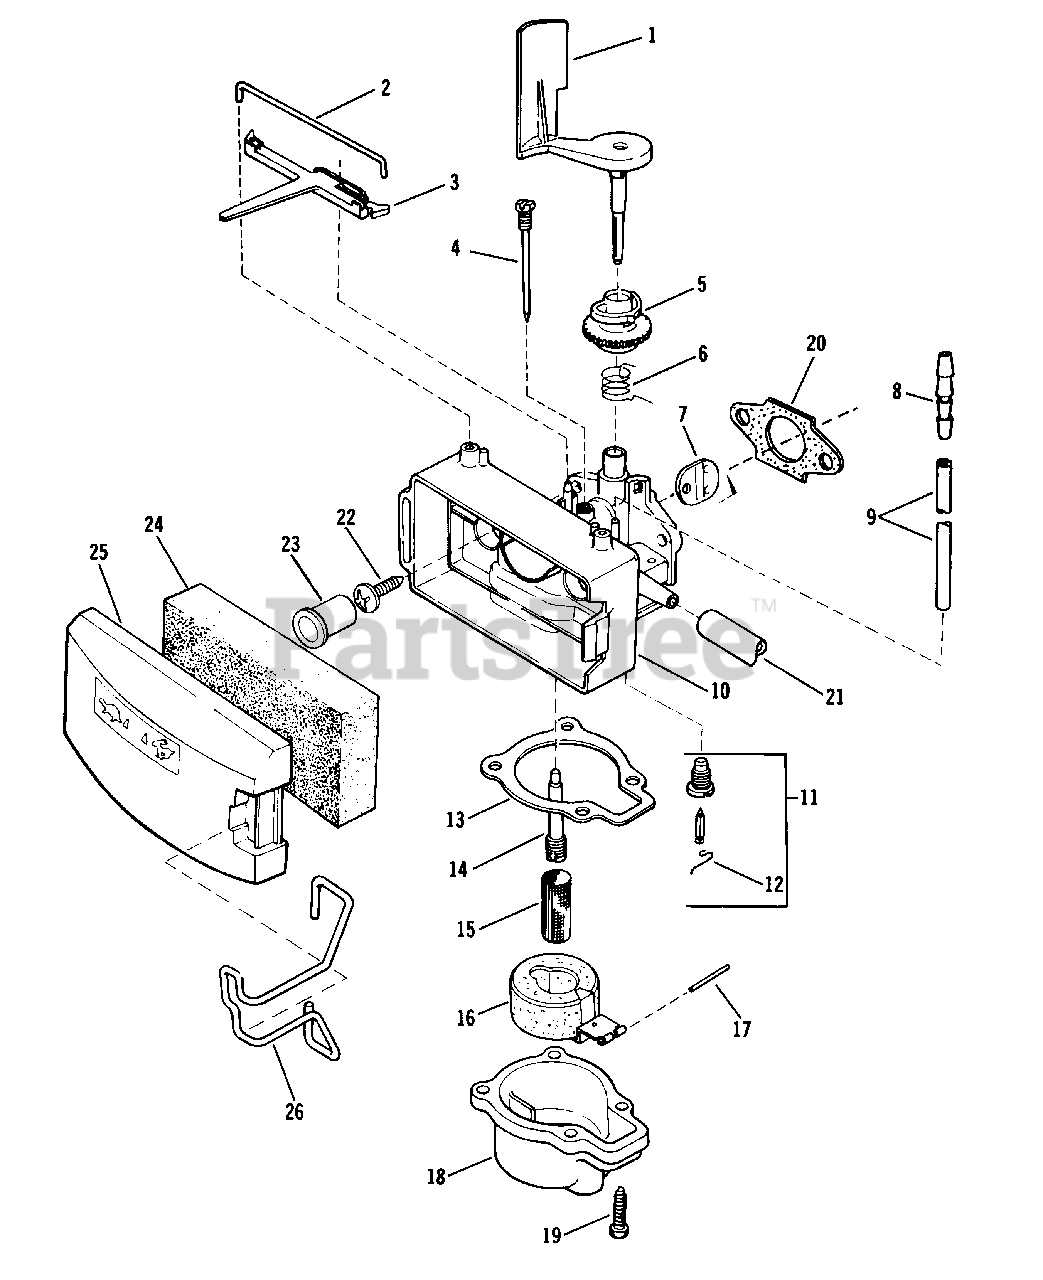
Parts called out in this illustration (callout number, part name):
1	Air Vane and Shaft
2	Retainer-Speed Control Lever
3	Speed Control Lever
4	Needle Adj. Assembly
7	Disc-Throttle
8	Connector-Reducer
9	Tube-Primer
10	Carburetor Body
11	Float Valve and Seat Assembly
12	Clip
13	Gasket
14	Nozzle
15	Filter-Carburetor
16	Float and Arm Assembly
17	Pin-Float
18	Float Chamber
19	Screw-Float Chamber
20	Gasket-Carb. to Crankcase Cover
21	Fuel Line
22	Screw-Carb. Mounting
23	Plug
24	Element-Air Filter
25	Cover-Air Filter
26	Retainer-Filter Cover
